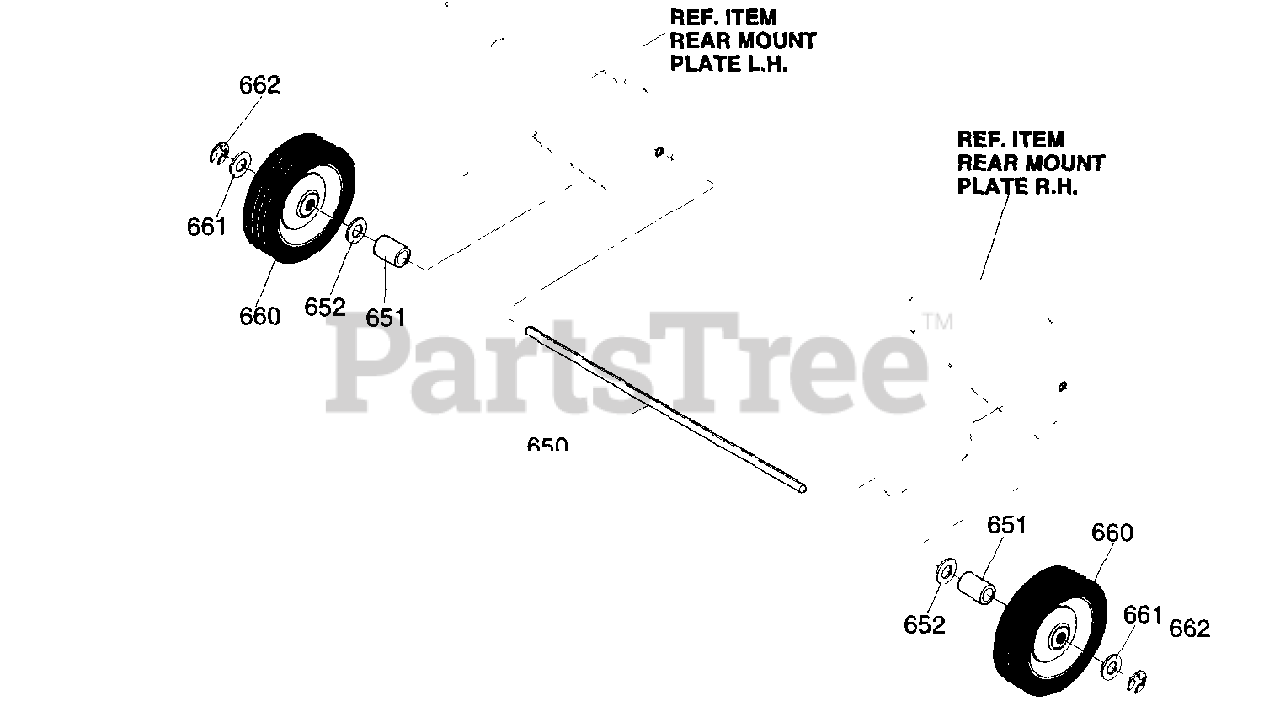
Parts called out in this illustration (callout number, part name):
650	AXLE SHAFT
651	SPACER, SLEEVE
652	FLATWASHER .406X.81X.065
660	TIRE & RIM 8X1.75
661	FLATWASHER .406X.81X.065
662	RING, RET.
